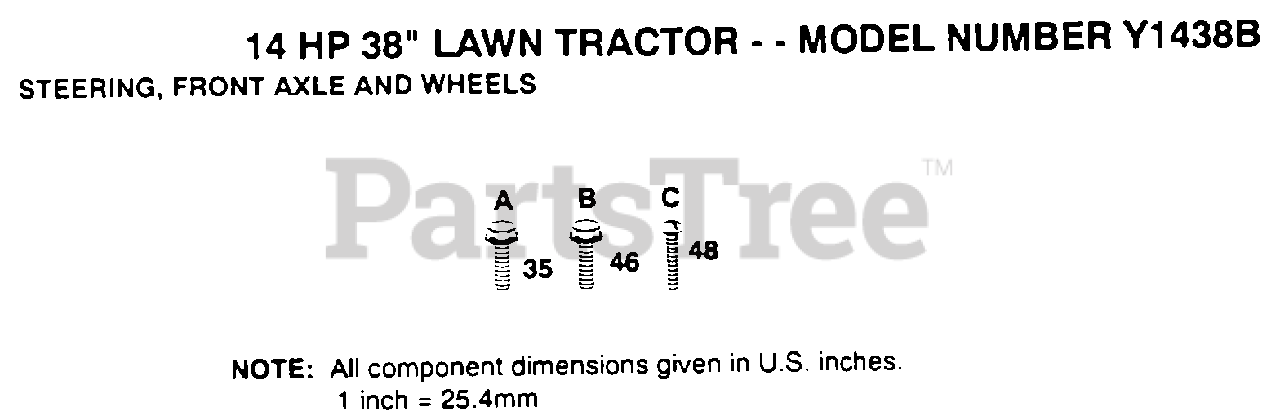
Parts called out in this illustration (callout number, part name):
35	SCREW
46	SCREW LT
48	SCREW SPECIAL
